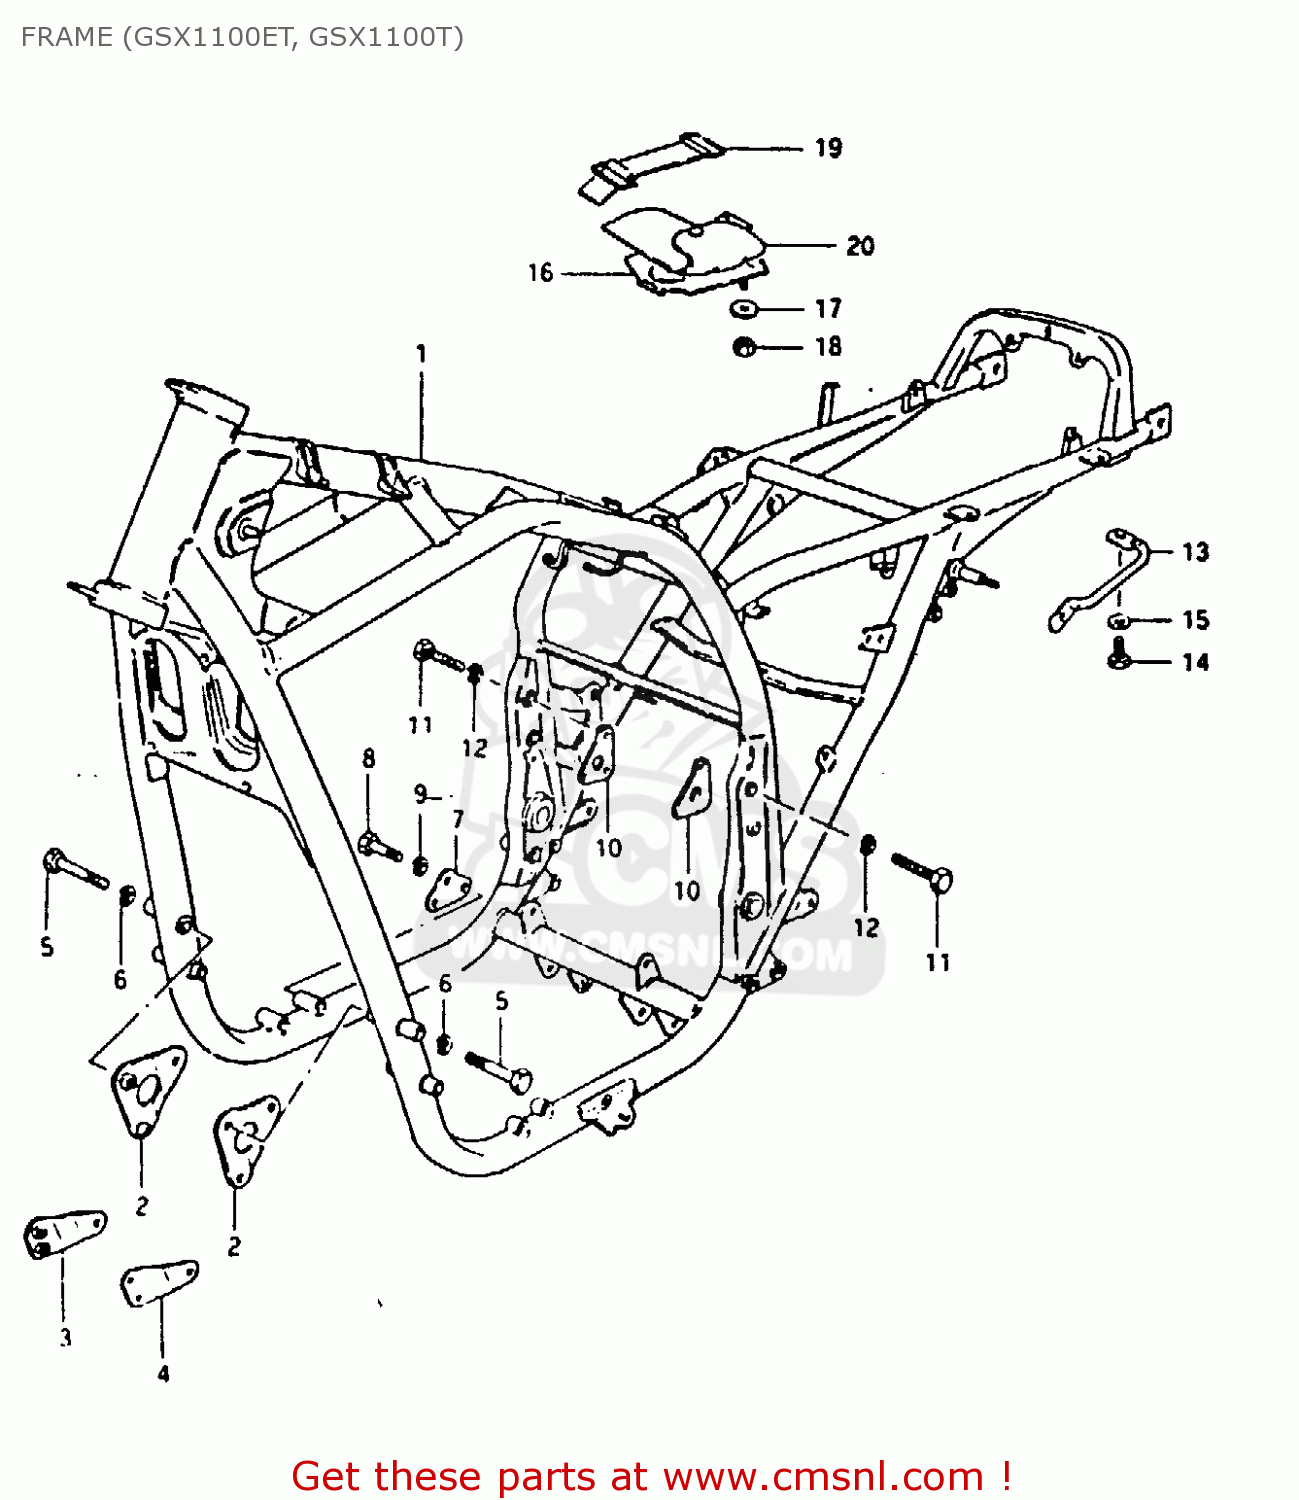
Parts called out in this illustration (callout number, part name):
1	FRAME (BLACK)
2	PLATE,ENG MTG NO.1
3	PLATE,ENGINE MOUNTING
4	PLATE,ENGINE MOUNTING
5	BOLT
6	LOCK WASHER
7	PLATE,ENGINE MOUNTING
8	BOLT
9	LOCK WASHER
10	PLATE,ENGINE MOUNTING
11	BOLT
12	LOCK WASHER
13	GRIP,FRAME
14	BOLT
15	WASHER
16	HOLDER,TOOL
17	WASHER
18	NUT
19	BAND
20	TOOL SET
